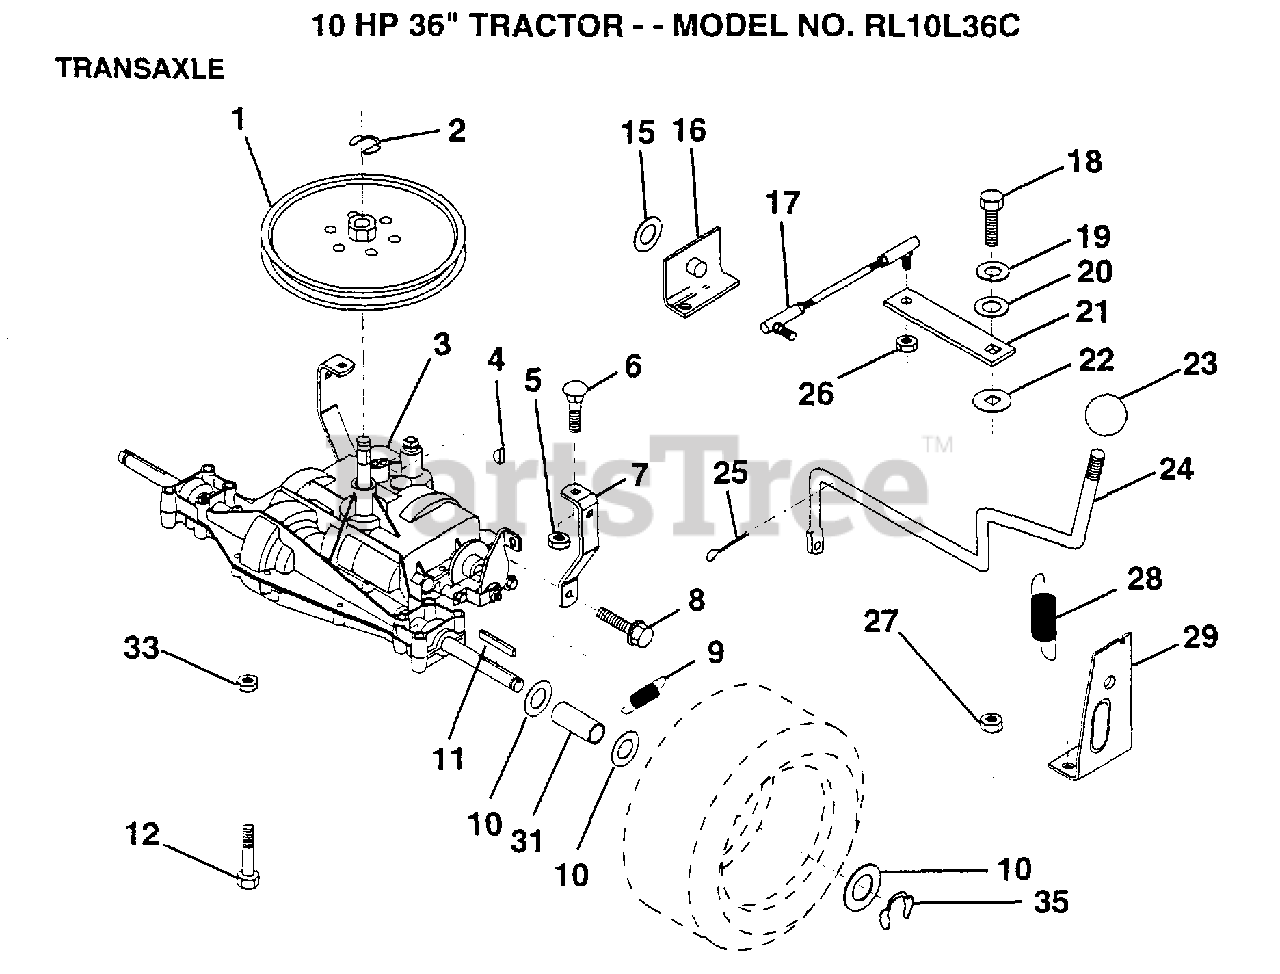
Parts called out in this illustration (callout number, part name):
1	PULLEY
5	NUT
6	BOLT
7	"STRAP,TORQUE"
8	SCREW
10	WASHER
11	SQUARE KEY
12	BOLT
16	"SUPT,HDLE SHT LH"
17	"LINK,SHIFT"
19	LOCKWASHER
20	WASHER LT
21	ARM SHIFT
22	WASH-SHFT PLT LT
23	KNOB T (1/2-HOLE)
24	"ROD,SHIFT"
25	PIN COTTER 1/8
26	NUT.LOCK.5/16-24
28	"SPRING,EXT"
29	"SUPT,HDLE RH"
31	SPACER LT
33	NUT
35	E-RING LT
